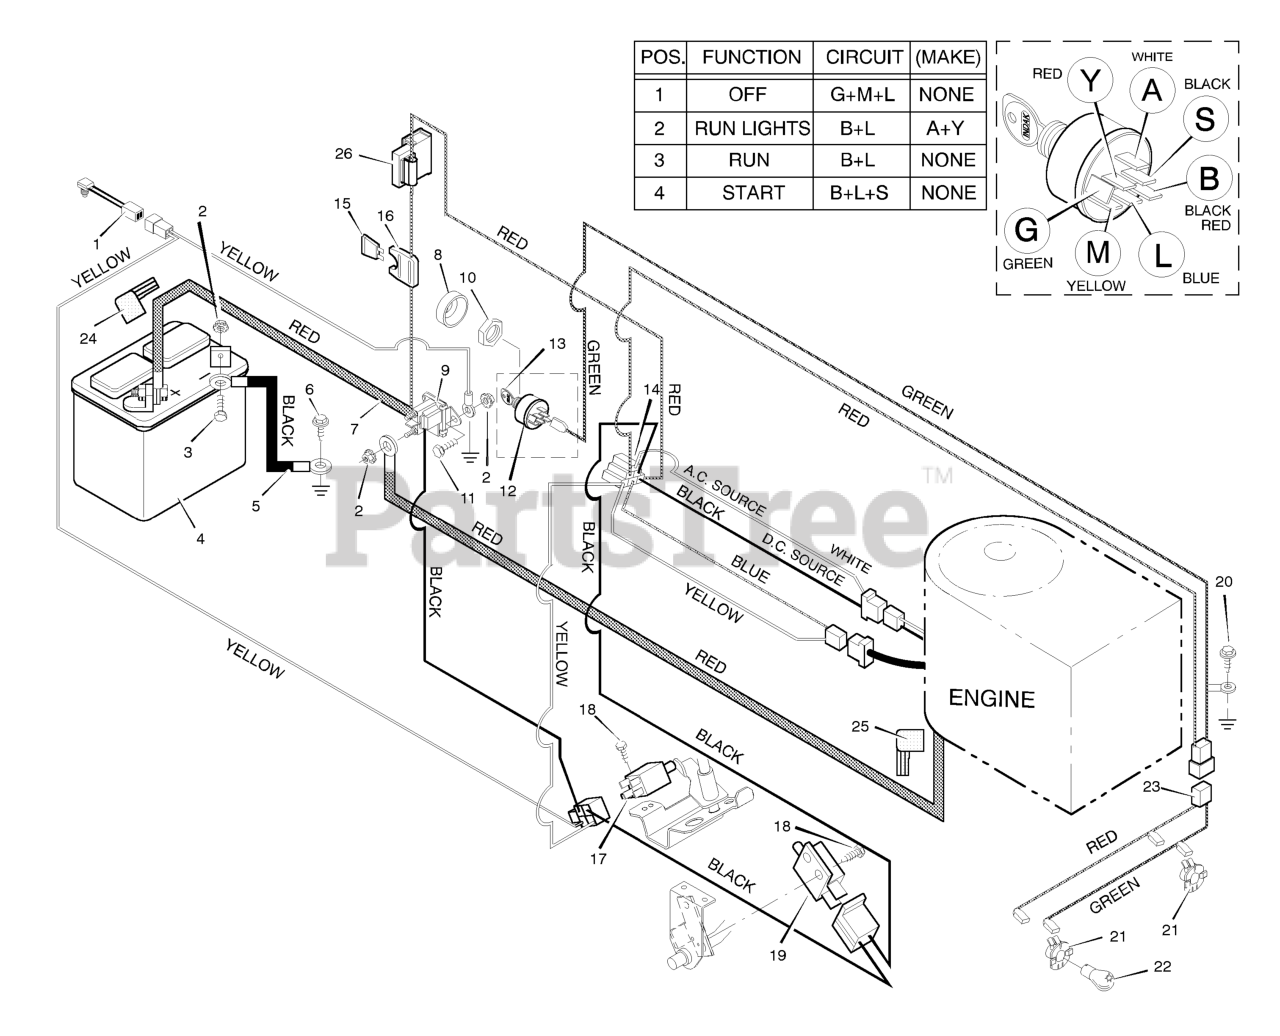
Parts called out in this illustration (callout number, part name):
1	Switch, Seat Sensor
2	Locknut
3	Bolt, Hex
4	Battery
5	Cable, Battery Ground
7	Cable, Red Battery
8	Cap, Ignition
9	Solenoid
10	Nut
12	Switch, Ignition
13	Key, Ignition
14	Harness, Chassis Wire
16	Holder, Fuse
17	Switch, Clutch
19	Switch, Clutch
20	Screw
21	Socket, Light
22	Bulb, Light
23	Harness, Light Wire
24	Cover, Terminal
25	Cover,
26	Ammeter
